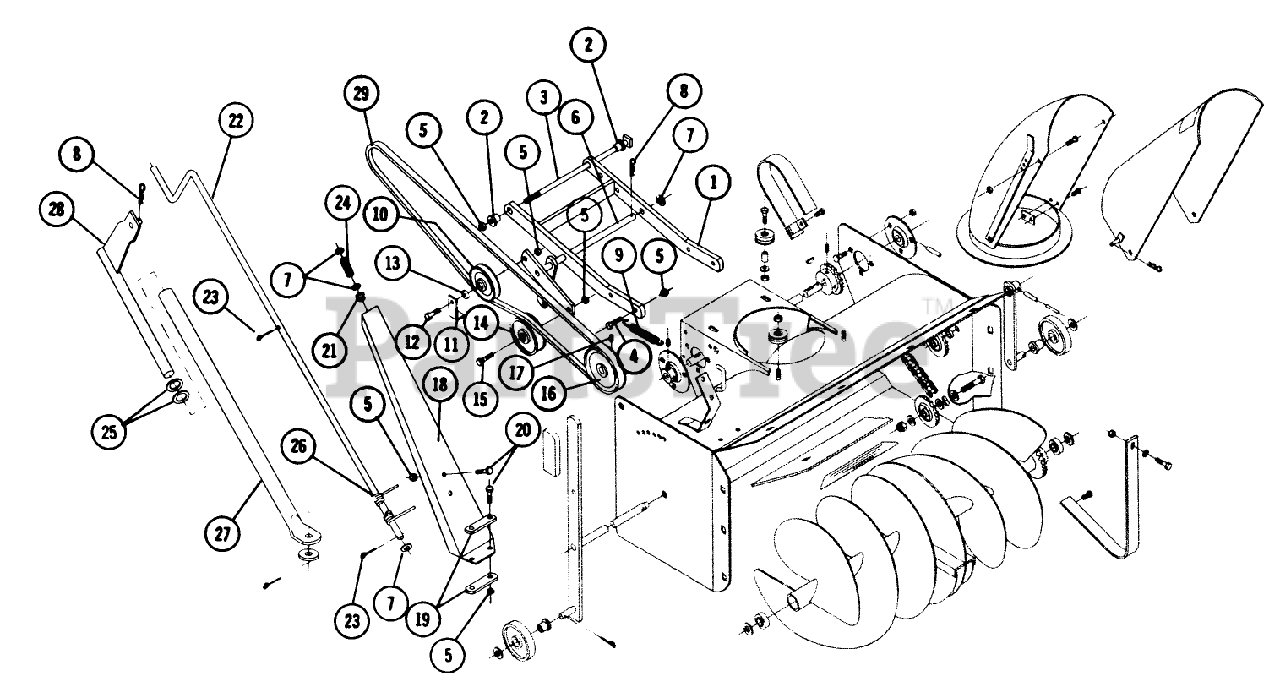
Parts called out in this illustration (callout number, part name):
1	Mounting Frame
2	Spacer
3	Bolt-Hex. 3/8-16 x 8 1/2
4	Bolt 3/8-16 x 7/8
6	ASSY IDLER ARM R
7	Washer
8	Hairpin
9	SPRING R
10	PULLEY-IDLER
11	Spacer
12	Bolt Hex 3/8-16
13	Spacer
14	Idler Pulley
15	Bolt, 3/8-16 x 1/2
16	Pulley
17	Set Screw
18	Crank Support
19	Bar-Reinforcing
20	Bolt 3/8-16 x 3/4
21	NYLINER BUSHING
22	Crank
23	Cotter Pin
24	SPRING-COMPRESSION
25	Washer
26	Cable
27	Tube-Lift
28	Lid Rod
29	V-BELT
